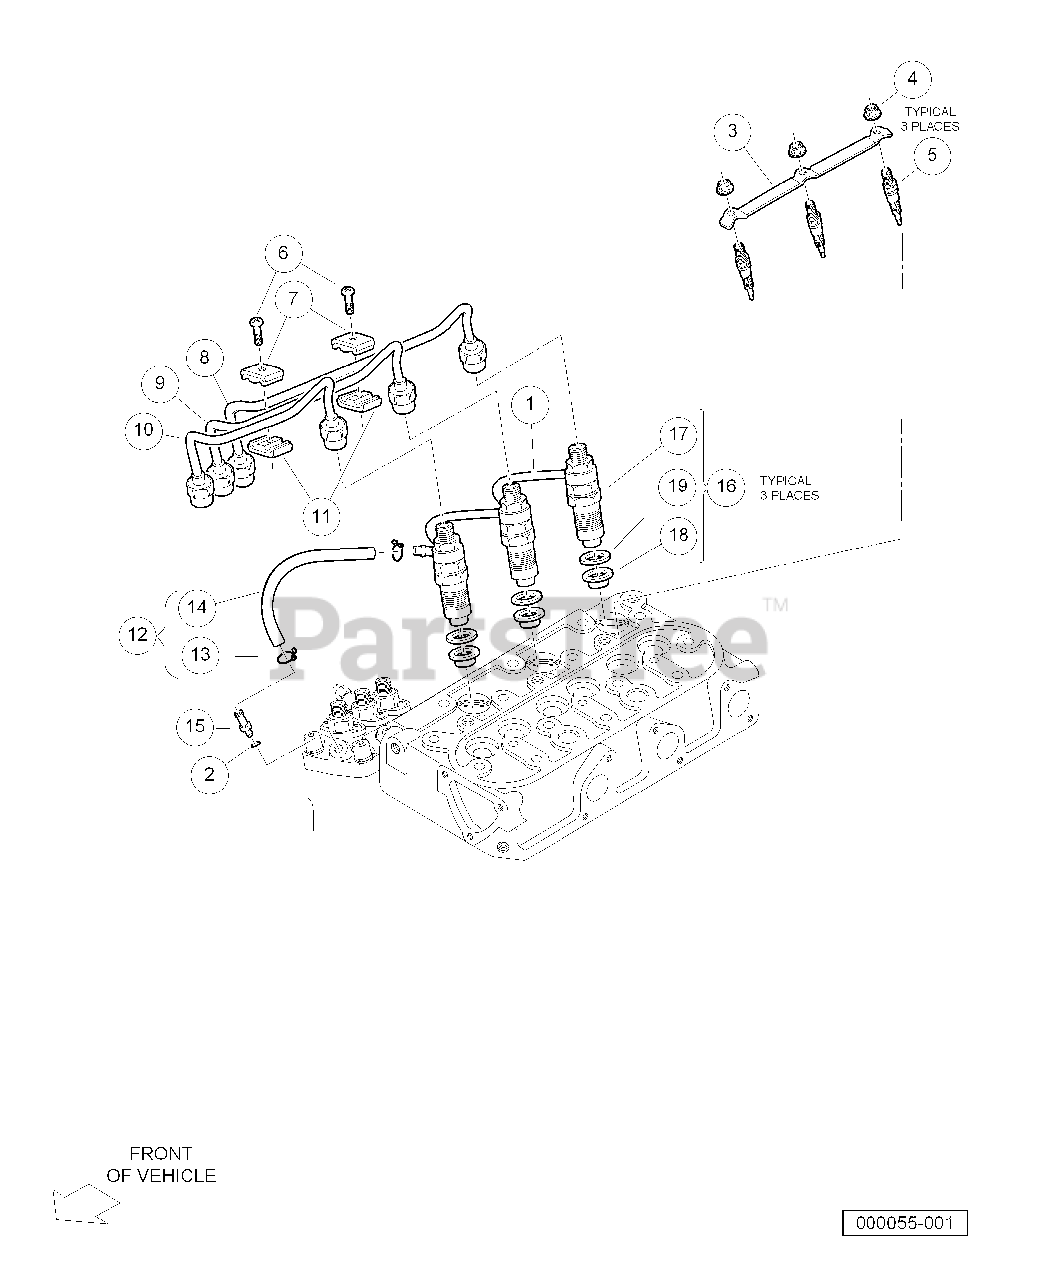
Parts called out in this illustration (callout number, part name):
1	Assy Pipe, D722 Fuel Over Flow
2	Gasket, 6 X 10
3	Cord, Glow Plug
4	Nut, Flange,m4
6	Screw, Washer
7	Clamp, Pipe, Top
8	Pipe, Injection, Left
9	Pipe, Injection, Right
10	Pipe, Injection, Middle
11	Clamp, Pipe, Bottom
12	Assy Pipe, Over Flow
13	Clip, Pipe, Return
14	Hose, Overflow
15	Screw, Air Bleeder
16	Kit, Holder, Nozzle
17	Assembly, Nozzle Holder
18	Seal, Heat
19	Gasket, Nozzle
